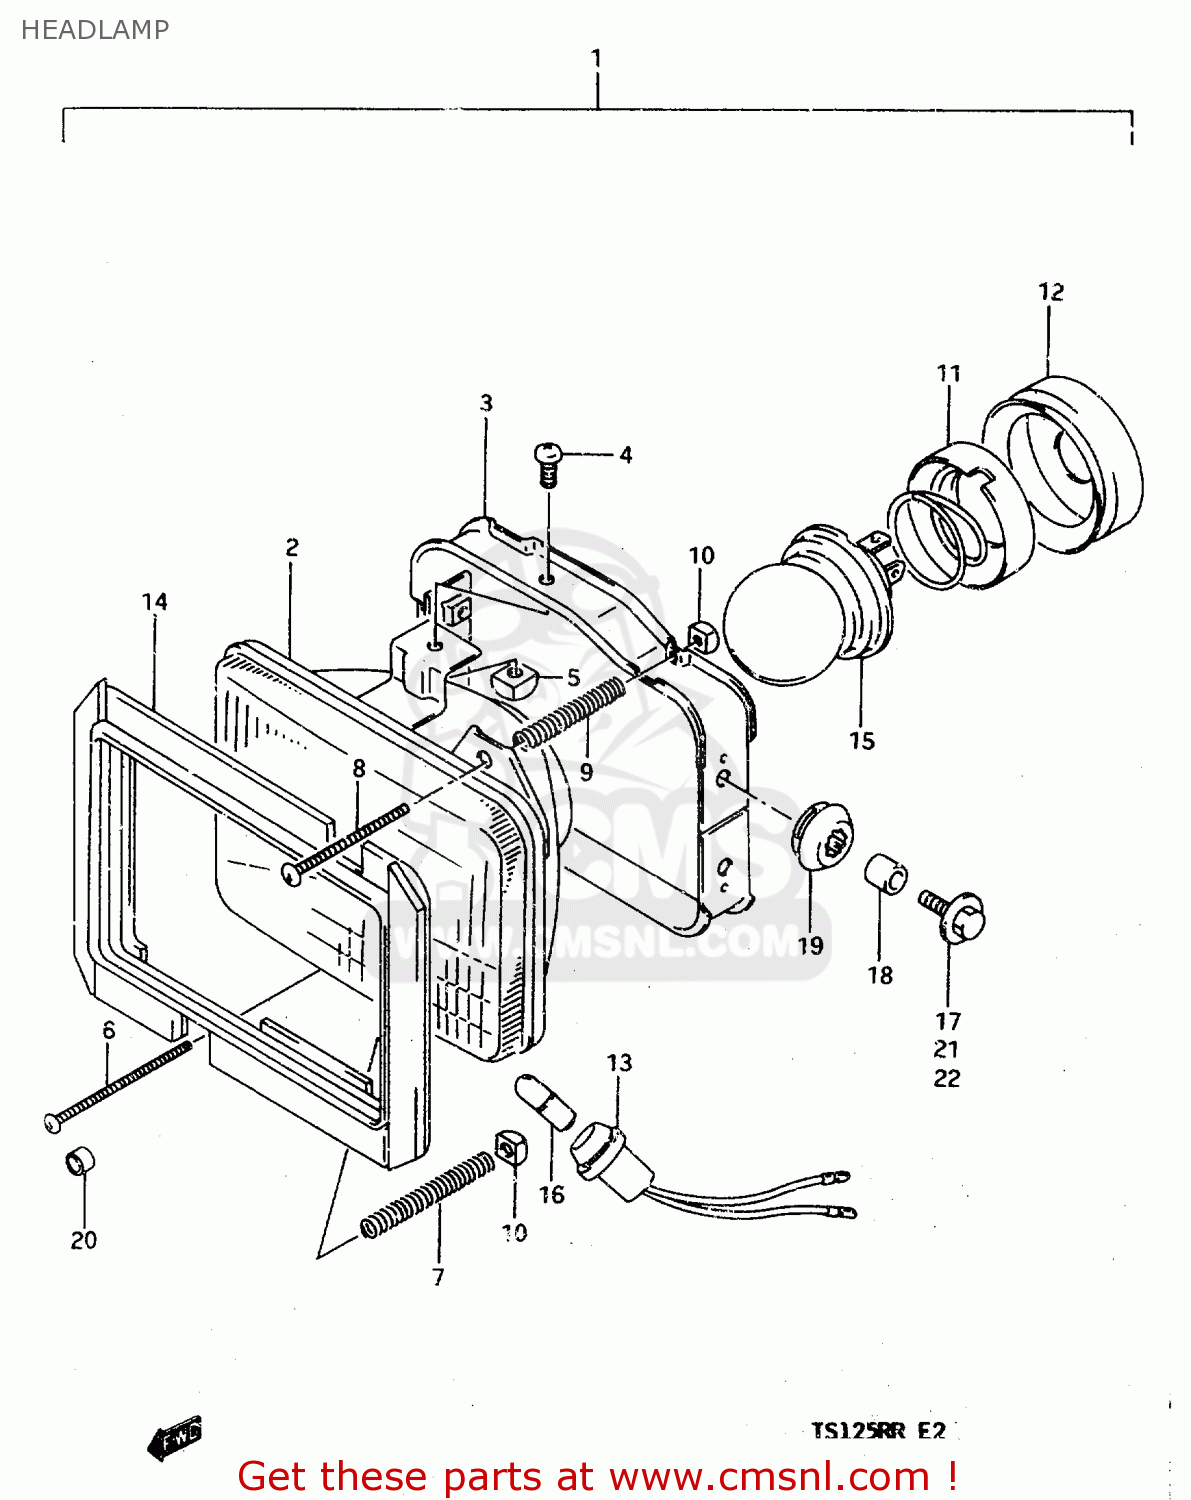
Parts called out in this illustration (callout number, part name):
1	HEADLAMP ASSY
2	UNIT
3	HOUSING
4	SCREW 5X12
5	NUT
6	SCREW
7	SPRING
8	SCREW,HEADLAMP ADJUST
9	SPRING
10	NUT
11	HOLDER,BULB
12	COVER,SOCKET
13	SOCKET
14	SHADE
15	BULB(12V45/40W)
16	BULB(12V4W)
17	BOLT 6X20
18	SPACER (6.8X10X10)
19	CUSHION
20	CAP,SCREW
21	BOLT
22	WASHER (6.5X20X1.2)
